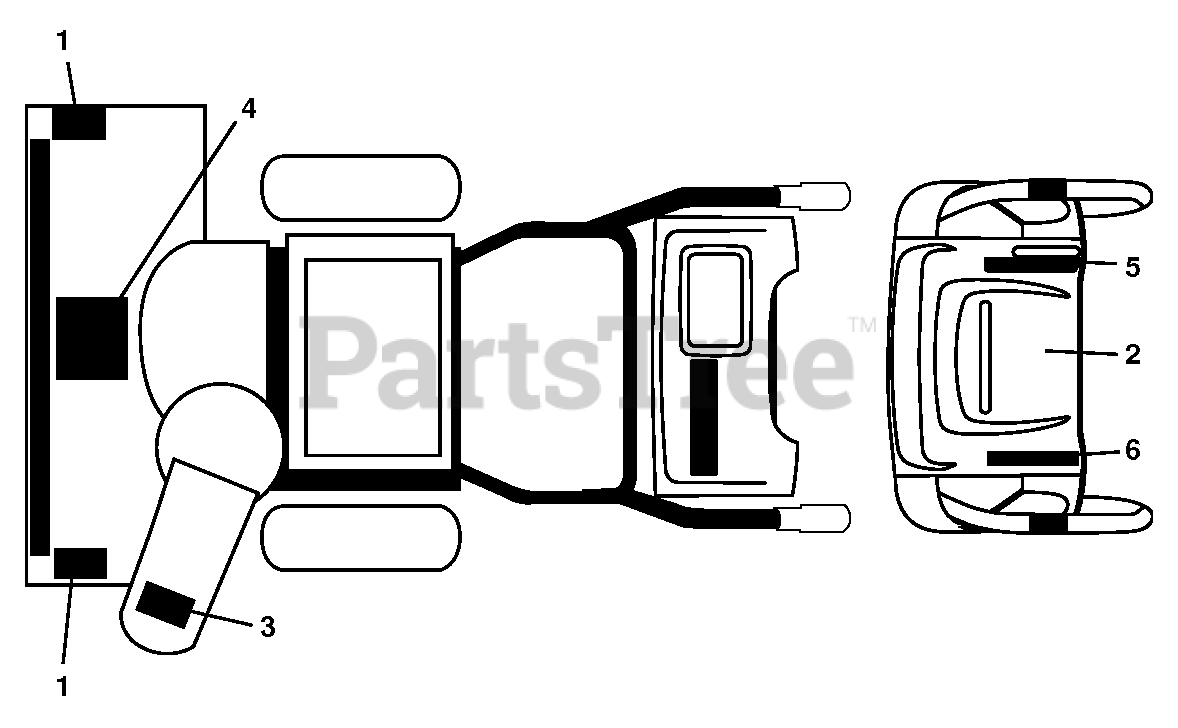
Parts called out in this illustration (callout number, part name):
1	DECAL.SNOWTHR.AUGER
2	Instruction Panel Decal
3	Decal, Snow Thrower Chute Safety
4	Decal, Snow Thrower Read Owner's Manual E/F
5	DECAL.CONS.RT.SPD/LEV/P.WRST
6	DECAL.CONS.LT.SPD/LEV/P.WRST
